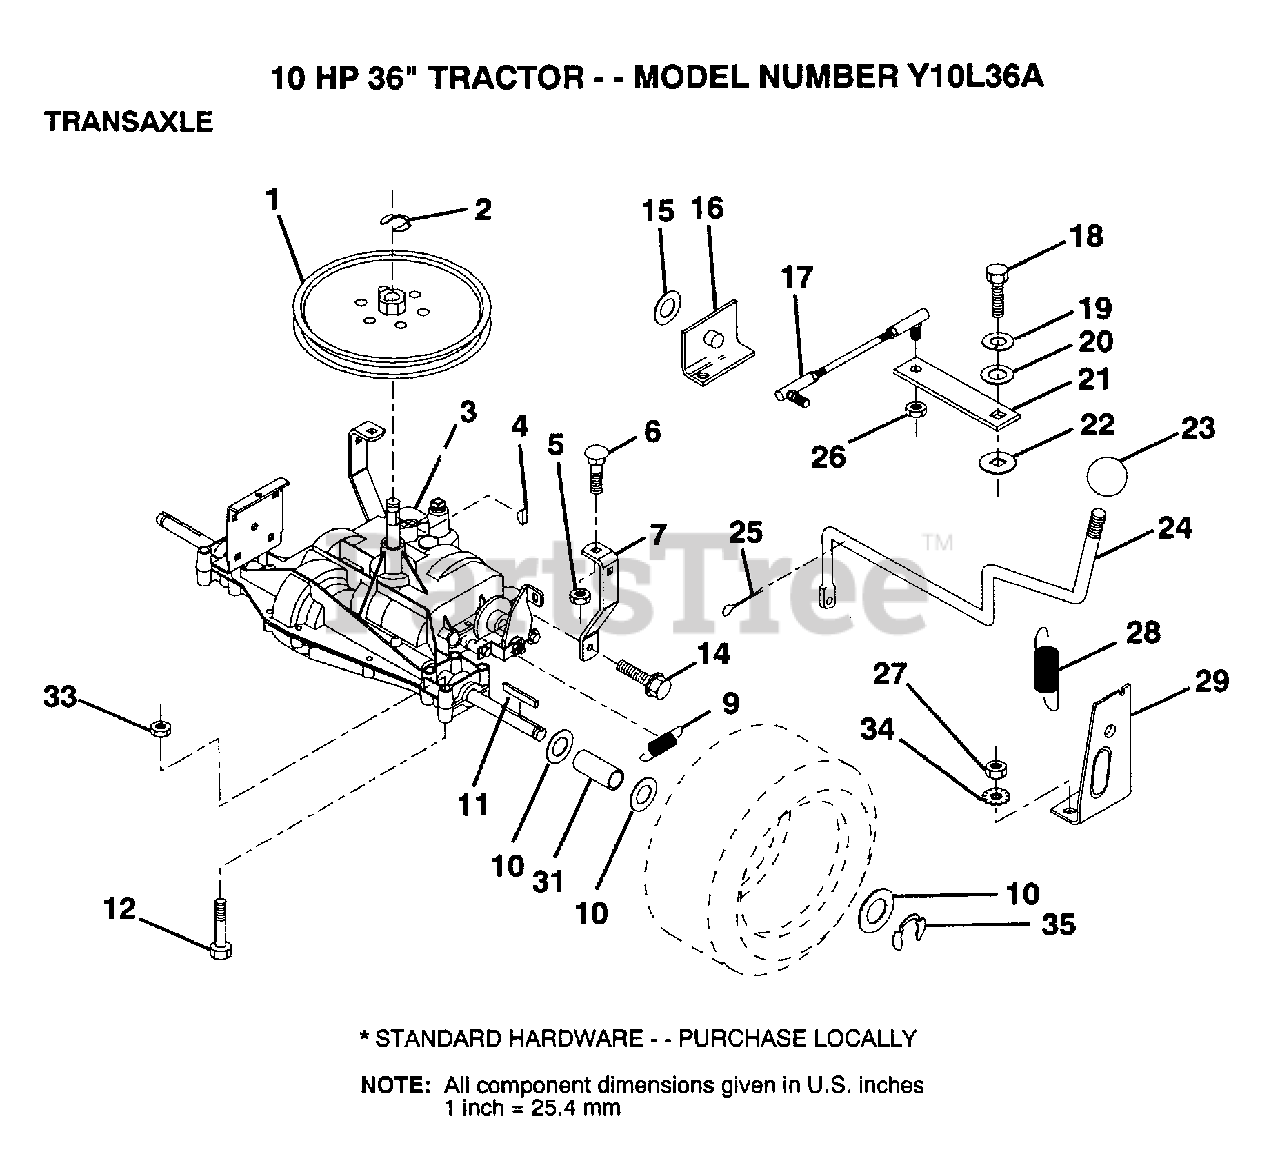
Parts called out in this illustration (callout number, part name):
1	PULLEY
6	BOLT
7	"STRAP,TORQUE"
10	WASHER
11	SQUARE KEY
12	BOLT
14	SCREW
16	"SUPT,HDLE SHT LH"
17	"LINK,SHIFT"
19	LOCKWASHER
20	WASHER LT
21	ARM SHIFT
22	WASH-SHFT PLT LT
23	KNOB T (1/2-HOLE)
24	"ROD,SHIFT"
25	PIN COTTER 1/8
26	NUT.LOCK.5/16-24
28	"SPRING,EXT"
29	"SUPT,HDLE RH"
31	SPACER
34	LOCKWASHER.5/16.E
35	E-RING LT
